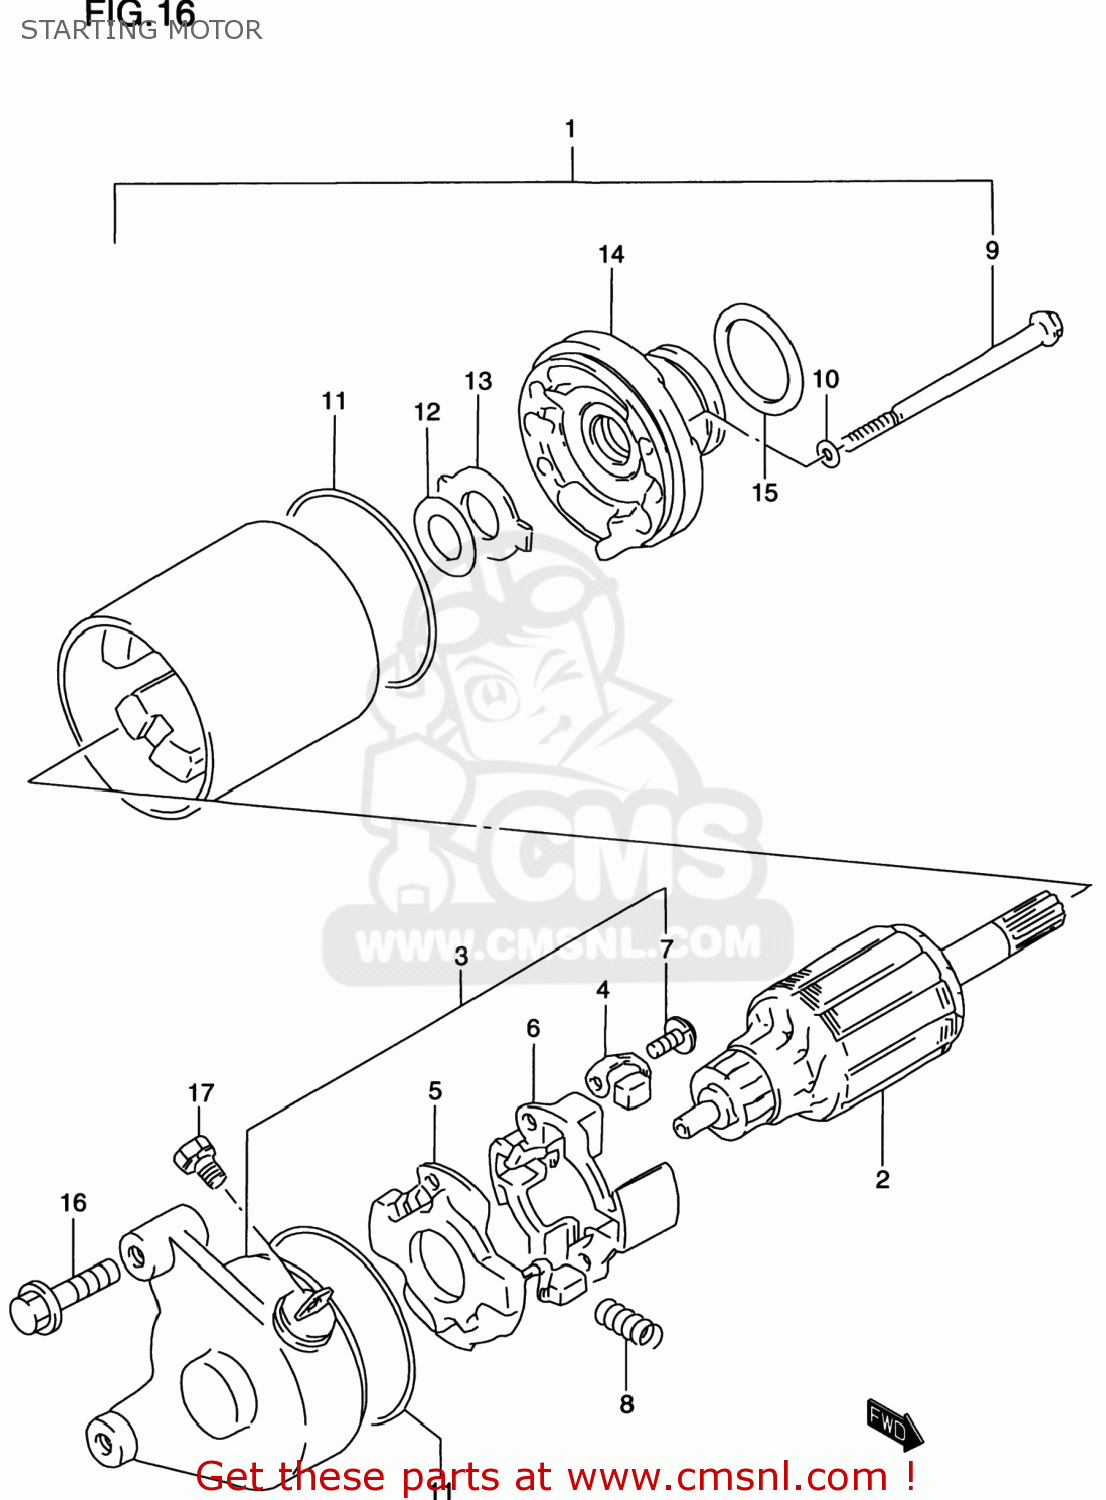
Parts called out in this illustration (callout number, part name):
1	MOTOR ASSEMBLY,STARTING
2	ARMATURE
3	FRAME ASSY,COMMUTATOR END
4	BRUSH
5	BRUSH SUB ASSY,STARTER
6	HOLDER,BRUSH
7	SCREW
8	SPRING
9	BOLT
10	O RING
11	O RING
12	SHIM
13	PLATE,LOCK
14	BRACKET
15	O RING(D:3,ID:24.5)
16	BOLT,G/S SWITC
17	SCREW(5X8)
